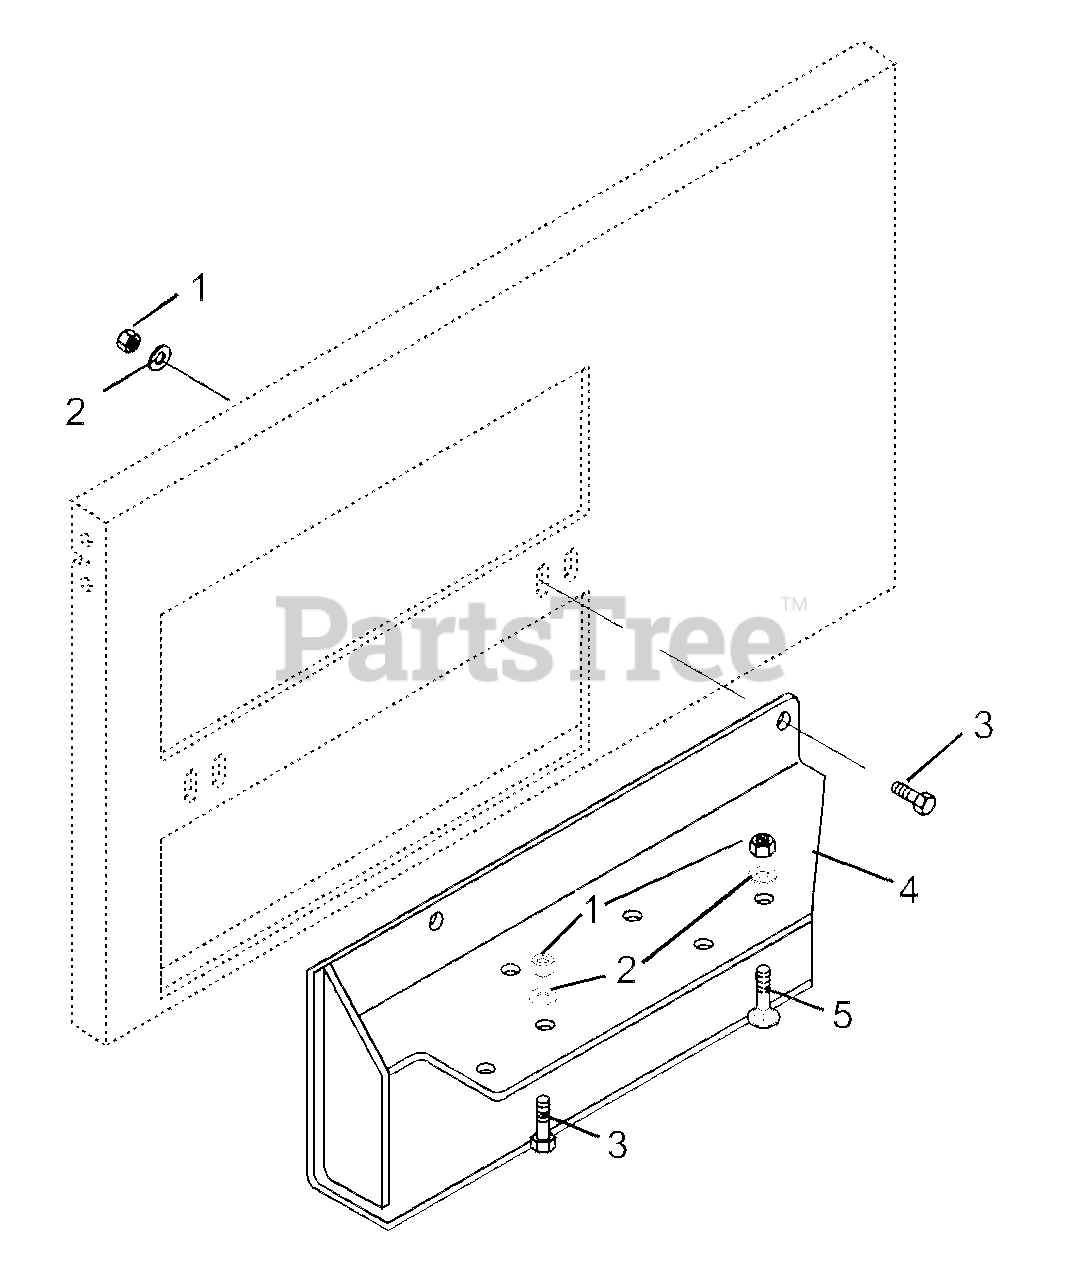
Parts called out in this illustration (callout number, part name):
1	Nut-Locking-Nylon .375-16 Grade 2
2	Washer-Flat-Steel .406 x .812 x .065
3	Bolt-Hex .38-16 x 1.00 Grade 5
4	Chute Adapter
5	Bolt-Round Head Square Neck .38-16 x 1.0
